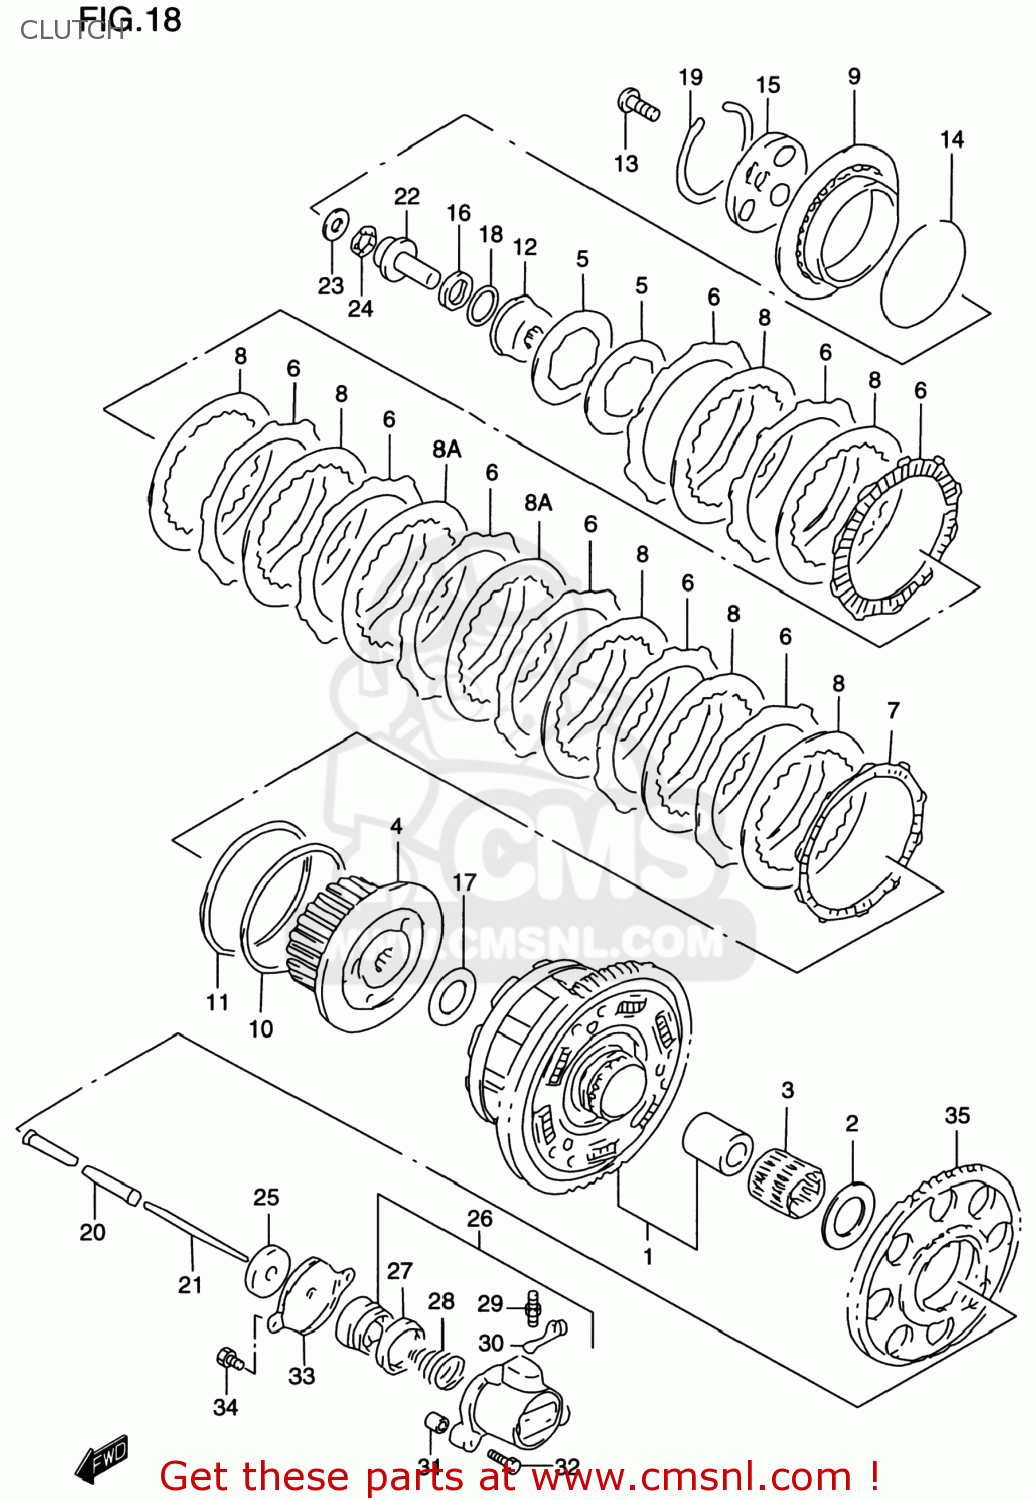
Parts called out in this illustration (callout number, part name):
1	GEAR ASSY,PRI DRIVEN
2	WASHER(25X54X2.5)
3	BEARING(35X40X35.8)
4	HUB,CLUTCH SLEEVE
5	SPRING,CLUTCH
6	PLATE,CLUTCH DRIVE
7	PLATE,CLUTCH DRIVE
8	PLATE,CLUTCH DRIVEN NO.1
8A	PLATE,CLUTCH DRIVEN NO.2
9	DISC,CLUTCH PRESSURE
10	SEAT,CLUTCH PLATE WAVE WASHER
11	WASHER,CLUTCH PLATE WAVE
12	HOLDER,CLUTCH SPRING
13	SCREW,CLUTCH SPRING HOLDER
14	SEAT,CLUTCH SPRING
15	LIFTER,CLUTCH PRESSURE DISC
16	NUT
17	WASHER(25X50X2.5)
18	WASHER
19	CIRCLIP
20	ROD,CLUTCH PUSH,R
21	ROD,CLUTCH PUSH,L
22	PIECE,CLUTCH PUSH
23	WASHER(15.5X28X1)
24	BEARING(15X28X2)
25	SEAL,OIL(6X34X5.5)
26	CYLINDER,CLUTCH RELEASE
27	CUP
28	SPRING,CLUTCH CYLINDER
29	BLEEDER
30	CAP,BLEEDER
31	PIN
32	BOLT,CL.COVER
33	COVER,CLUTCH RELEASE CYLINDER
34	SCREW
35	GEAR,GENERATOR DRIVE
